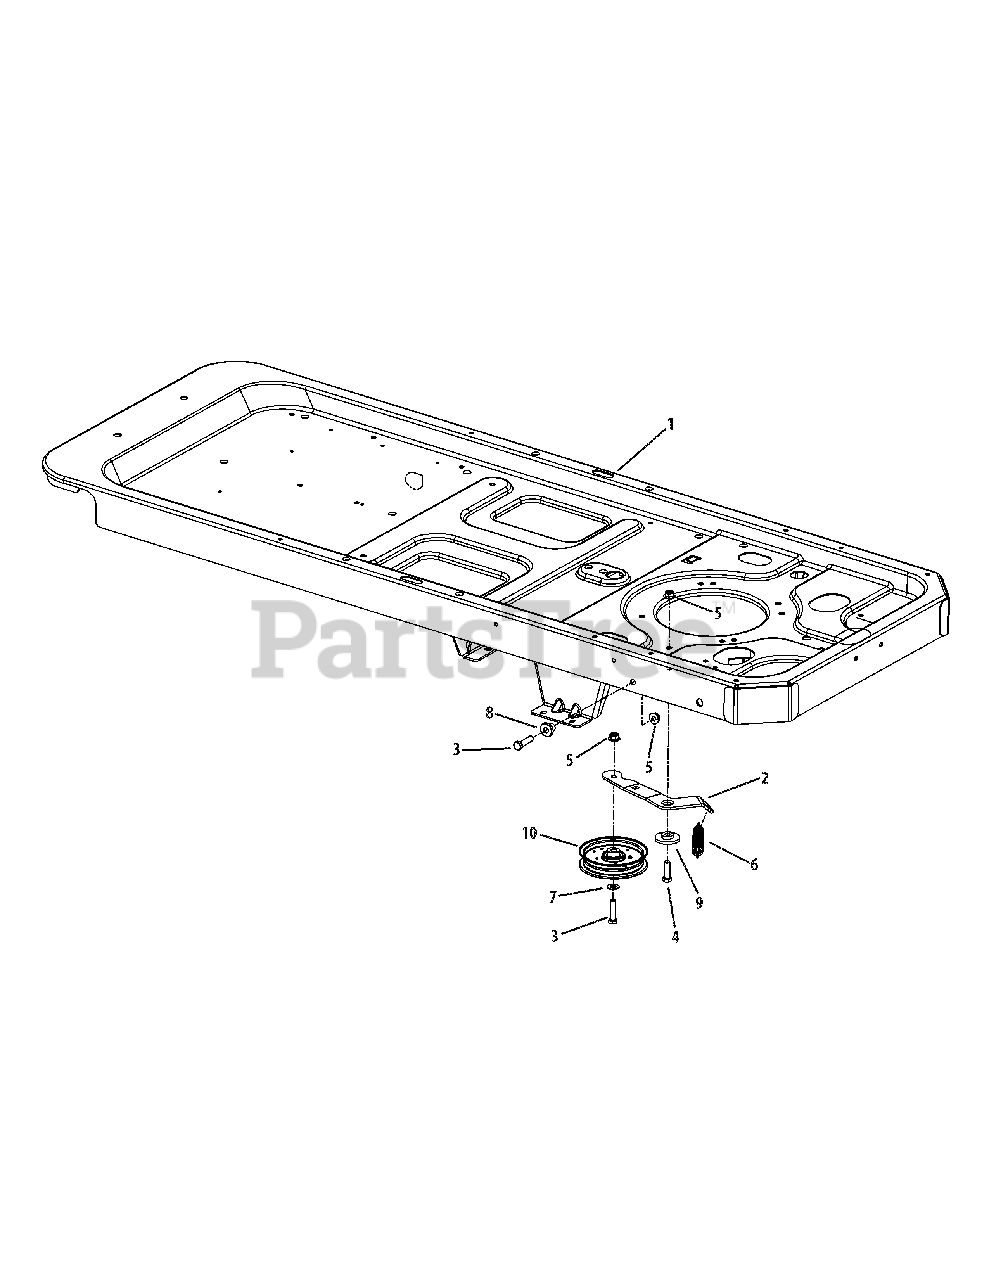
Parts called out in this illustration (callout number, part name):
1	Frame
2	Idler Arm
3	Hex Cap Screw, 3/8-16 x 1.5
4	Hex Cap Screw, 3/8-16 x 1.25
5	Hex Flange Lock Nut, 3/8-16
6	Extension Spring, .75 x 5.06
7	Flat Washer, .406 x .875 x.059
8	Shoulder Spacer, .38 x 1.0 x .7
9	Shoulder Spacer, .884 x 1.9
10	Idler Pulley
